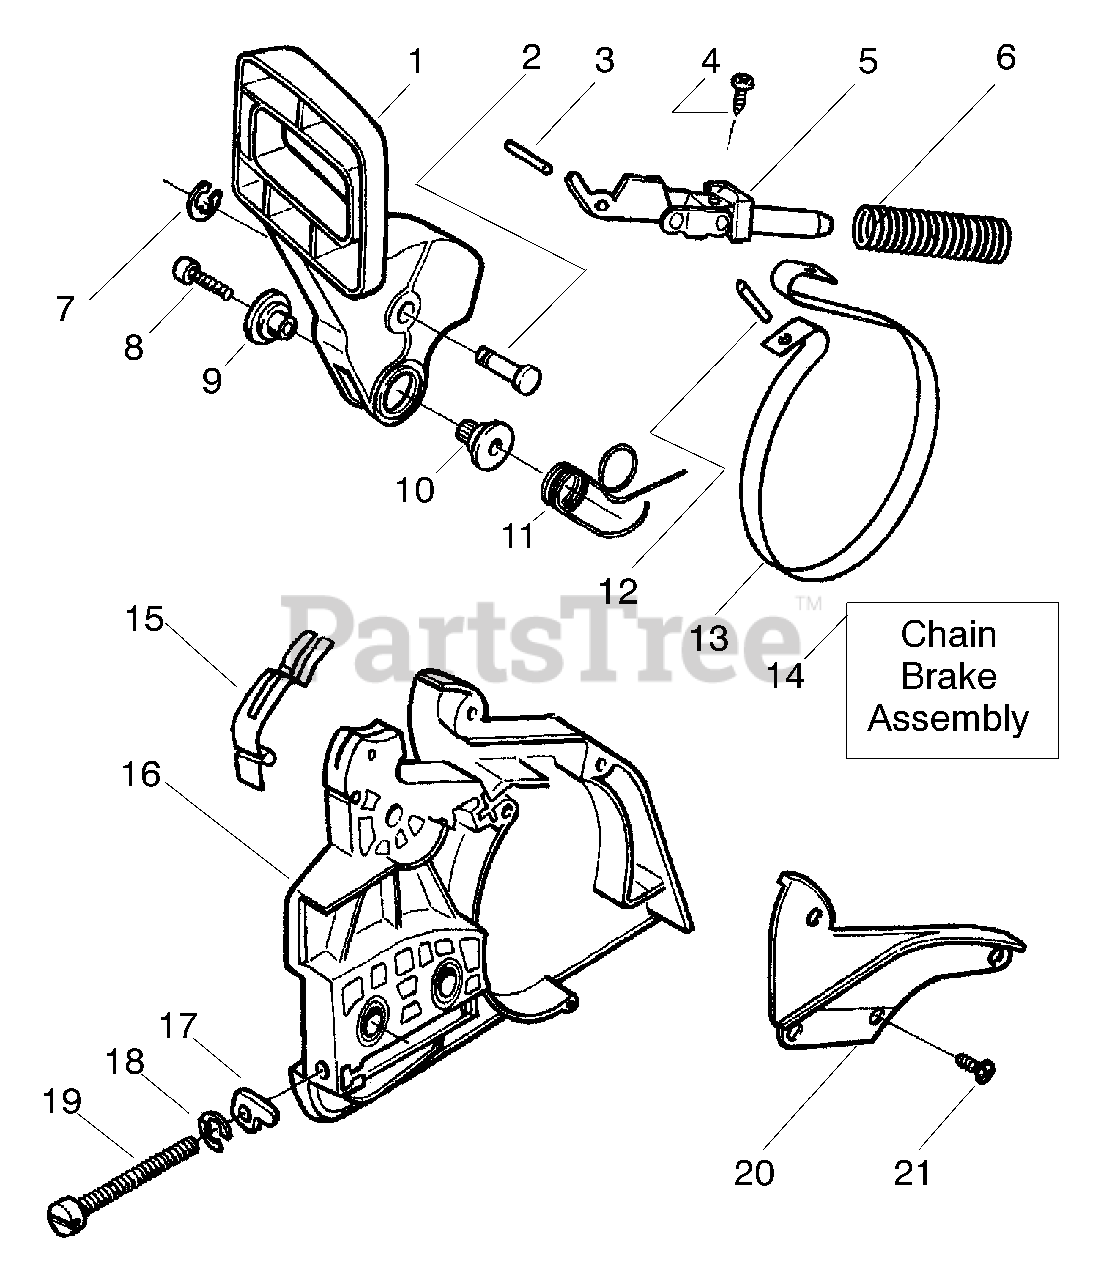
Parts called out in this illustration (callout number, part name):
1	Kit- Lever & Link Assy.
4	Screw
5	Assy-Front Link
6	Spring-Chain Brake
9	Journal-Right
10	Journal-Left
11	Spring-Handguard
12	Pin-Spring
13	Band-Brake
14	Assy-Chain Brake
15	Spring-Position
16	Cover-Clutch
17	Pin-Bar Adjusting
19	Screw-Bar Adjusting
20	Cover-Chain Brake Spring
21	Screw
